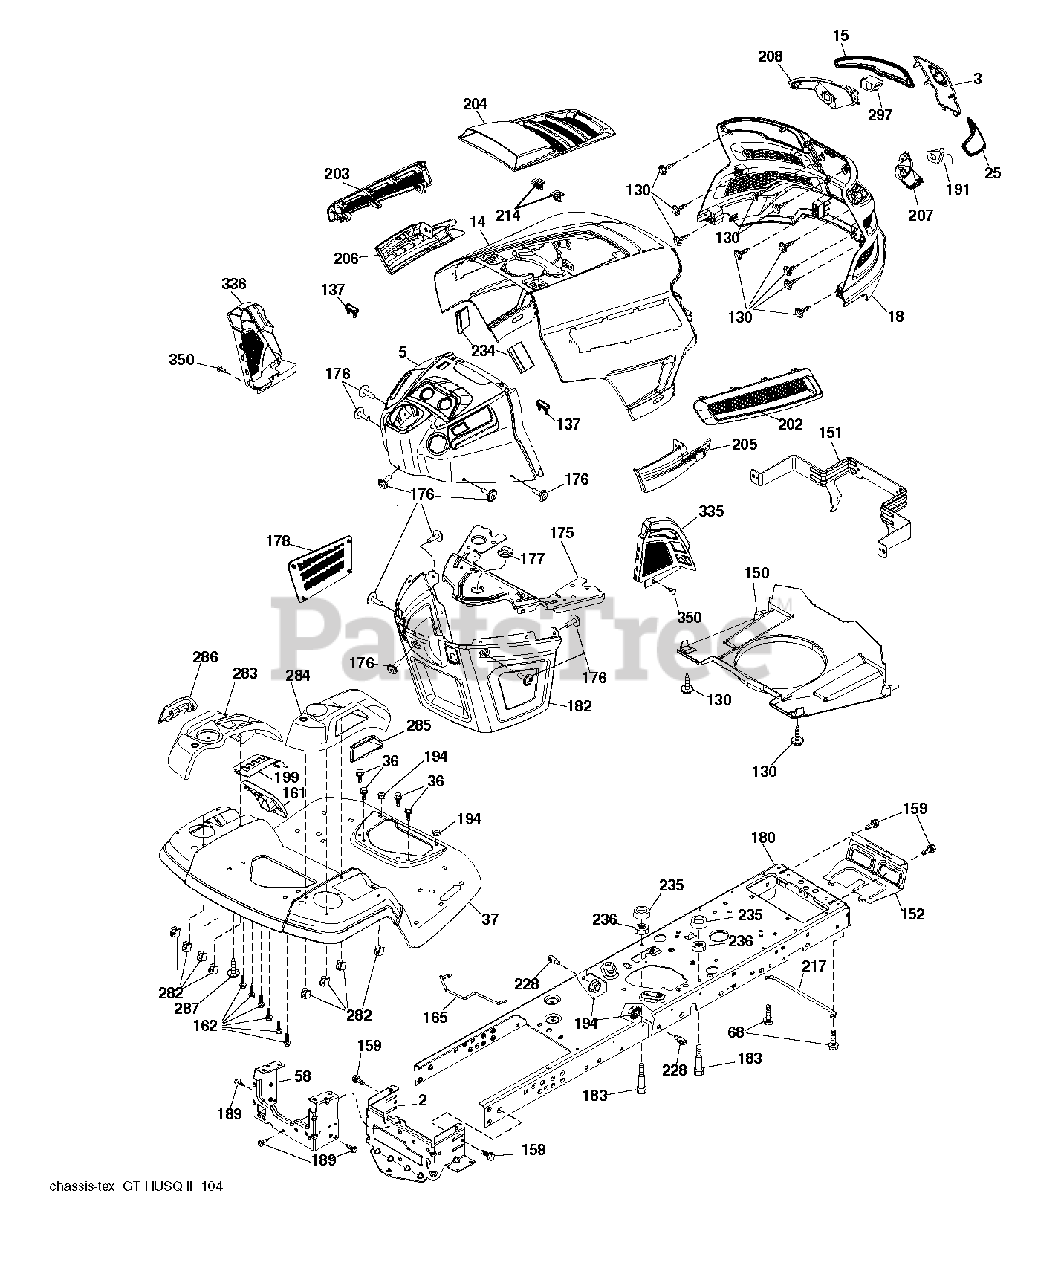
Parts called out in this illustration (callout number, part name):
2	DRAWBAR.LOWER.2PC.18/22
3	APPLIQUE.SUBASM.GT.HUSQ.II
5	DASH.UPP.GT2.DUAL.RD.PTO.MCHOK
14	HOOD.ASM.HUSQVARNA.GT.TEX.ORAN
15	LENS.HEADLIGHT.LH.GTII.2011
18	GRILLE.SUBSTRATE.2011.
25	LENS.HEADLIGHT.RH.GTII.2011
36	SCREW 5/16"
37	FENDER.TLT.FS.W/CPH/FW/RSF.668
58	DRAWBAR UPPER 2PC SMALL FENDER
68	SCREW LT
130	SCREW.#10 X 0.750.BOS
137	BUMPER DASH
150	AIR.DUCT.GTV.BLACK
151	BRACKET.PIVOT.HOOD.GT.HUSQ.II
152	SHIELD.BROWNING.PNT.GT.V2
159	SCREW, 3/8-16X3/4
161	WINDOW.FUEL.LT.HUSQ.TEX.498
162	SCREW.HI-LO.CONSOLE
165	SUPPORT.TANK.REAR.B/TE
175	PLATE.CROSSMEMBER.HUSQ
176	SCREW.#10-24X5/8.RN.QU
177	BUSHING, STEERING
178	CARGO.ASM.NET.TXGT.W/C
180	CHASSIS.STAMPING.LT/GT
182	DASH.LOWER.COMMON.12V.ADAPTOR
183	BOLT.5/16-18X1-1/4 FULL THD
189	SCREW
191	INSERT.REFLECTIVE.RH.HUSQ.GTII
194	NUT LOCK HEX FLANGE 5/16-18
199	PLATE.DECK.LIFT.HUSQ.LT
202	VENT.SIDE.RH.GT.HUSQ.II.
203	VENT.SIDE.LH.GT.HUSQ.II.498
204	VENT.TOP.HUSQ.GT2
205	SIDE.TRIM.RH.GT.HUSQ.II
206	SIDE.TRIM.LH.GT.HUSQ.II.GRAY
207	BEZEL LIGHT.RH.GT.II.MYLAR
208	BEZEL LIGHT.LH.GT.II.MYLAR
214	CLIP.RETAINER.TINNER.
217	ROD.PIVOT.HOOD
228	STUD.FASTNER.W/ANTI-ROTATE
234	BUMPER.HOOD.TEX.HUSQVARNA
235	SPACER FENDER
236	NUT.CENTERLOCK.5/16-
282	CLIP.RETAINER.CONSOLE.LT.HUSQ
283	CONSOLE.DECK.LIFT.R.SDFL.HUSQ
284	CONCOLE.CNTRL.PDL.HUSQ.LT.498
285	CONSOLE INSERT RH
286	CONSOLE.INSRT.LH.HUSQ.LT.BLACK
287	SCREW 1/4X20
297	INSERT.REFLECTIVE.LH.HUSQ.GTII
335	COVER.LOWER.DASH.RH.BLACK
336	COVER.LH.CLOSE.OUT
350	CLIP.X-MAS.TREE
